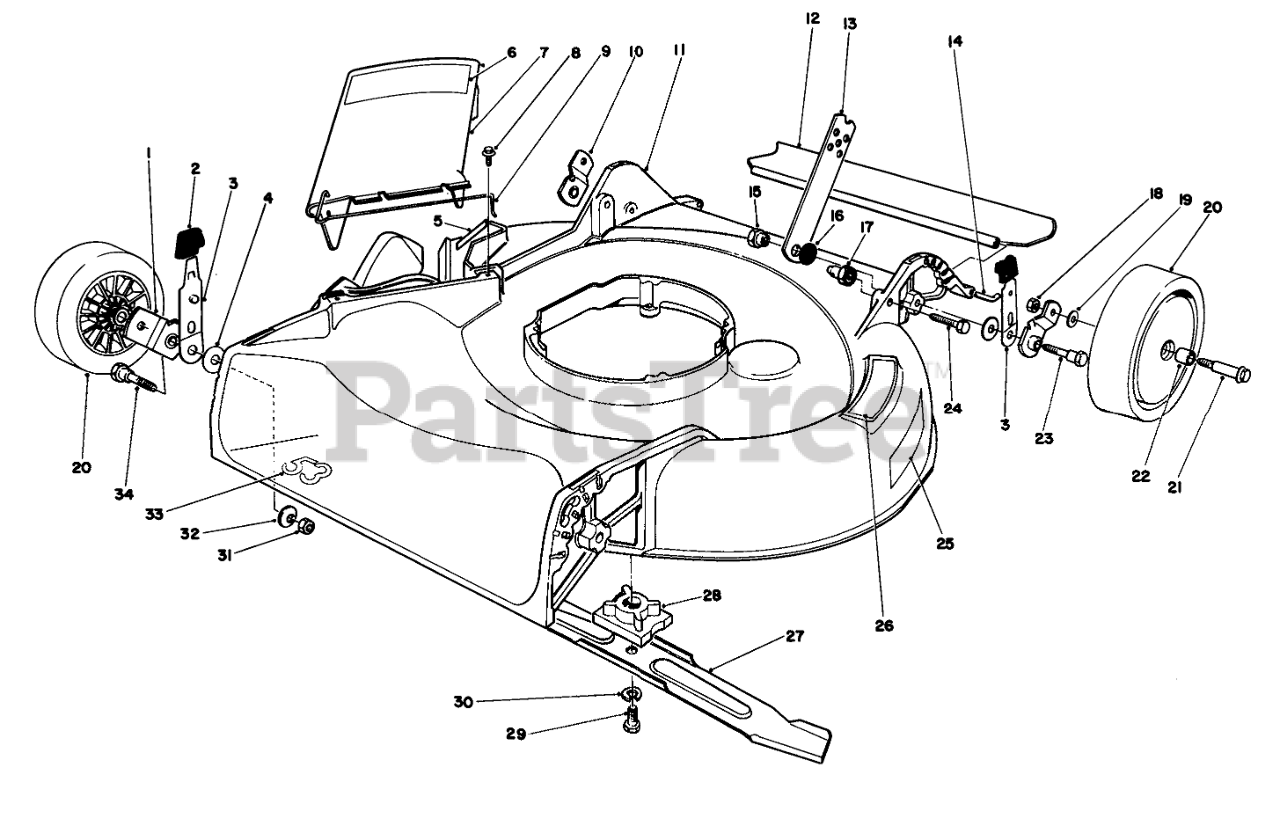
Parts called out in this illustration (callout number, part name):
1	Pivot Arm
2	KNOB-ARM
3	SPRING ARM ASM
4	WASHER-PIVOT
5	DANGER DECAL
6	DECAL - DANGER DEFL
7	Deflector (Incl. Ref. #6)
8	SCREW-HWH
9	SPRING HINGE
10	Pivot Arm
11	Housing (Incl. Ref. #25 & 26)
12	REAR SAFETY SHIELD 21
13	HANDLE LATCH
14	SHIELD ROD
15	HANDLE PIVOT NUT
16	SPACER
17	HANDLE PIVOT NUT
18	Nut
19	WASHER
20	Wheel & Tire Assembly (Incl. Ref. #23)
21	WHEEL BOLT
22	BUSHING
23	PIVOT SCREW
24	SCREW-HH
25	Decal Danger
26	DECAL - STEP PAD INT'L
27	Blade
28	BLADE RETAINER
29	SCREW-HH
30	WASHER-LOCK
31	NUT-LOCK, NI
32	WASHER-BELLEVILLE
33	DECAL - 53
34	5/16-18 PIVOT SCREW
